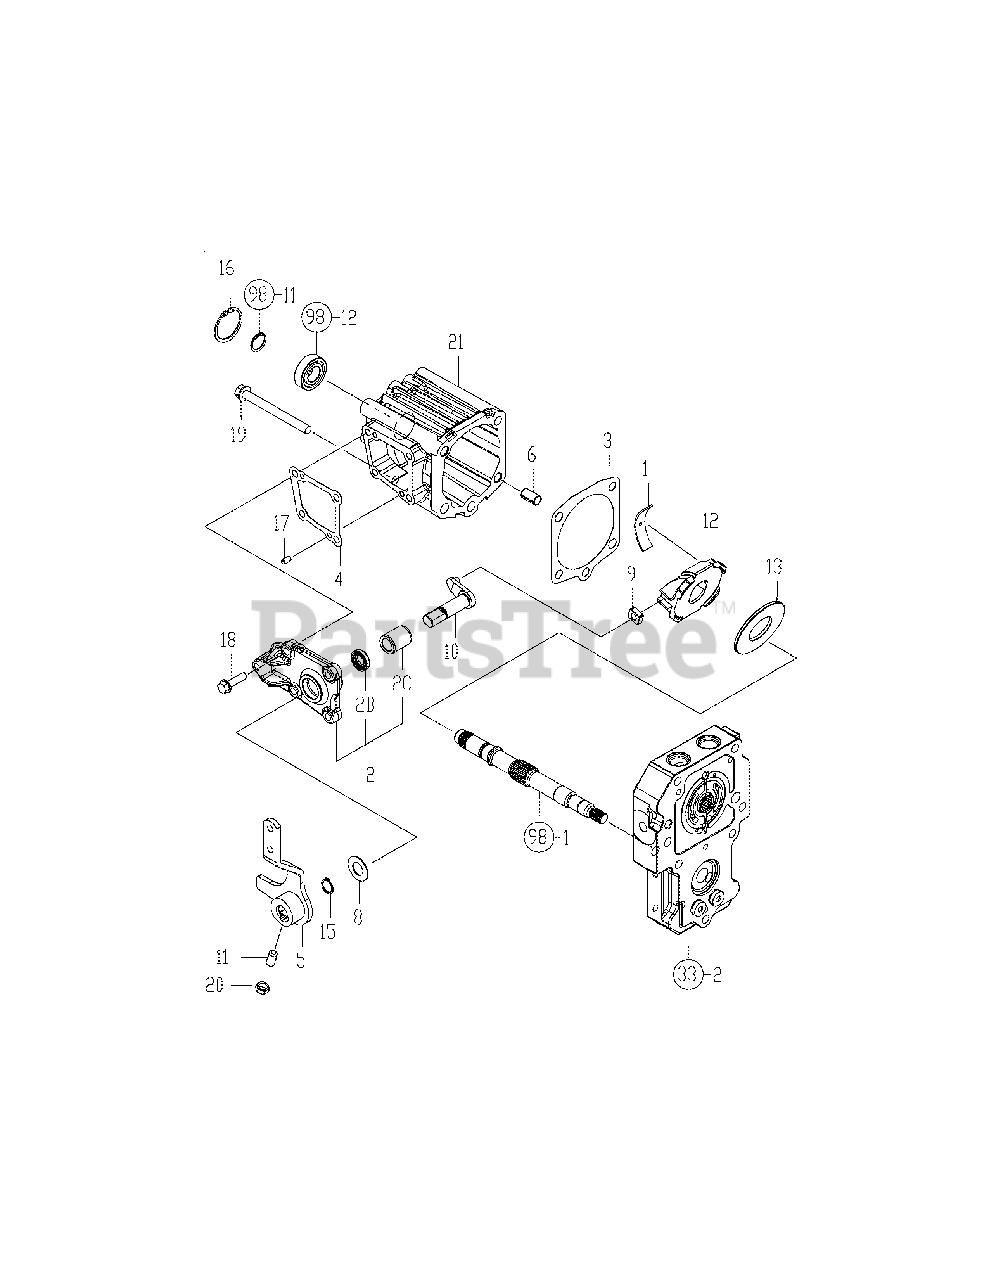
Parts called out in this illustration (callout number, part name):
1	Thrust Metal (Ddr16
2	Side Cover, Cmp
3	Packing, Motor Case
4	Paking (Side Cover
5	Second Lever Cmp
6	Pin, Knock 12X22
8	Washer 17X32X1
11	Set Screw 10X20
19	Bolt, 10 X 105
21	Motor Case K93
